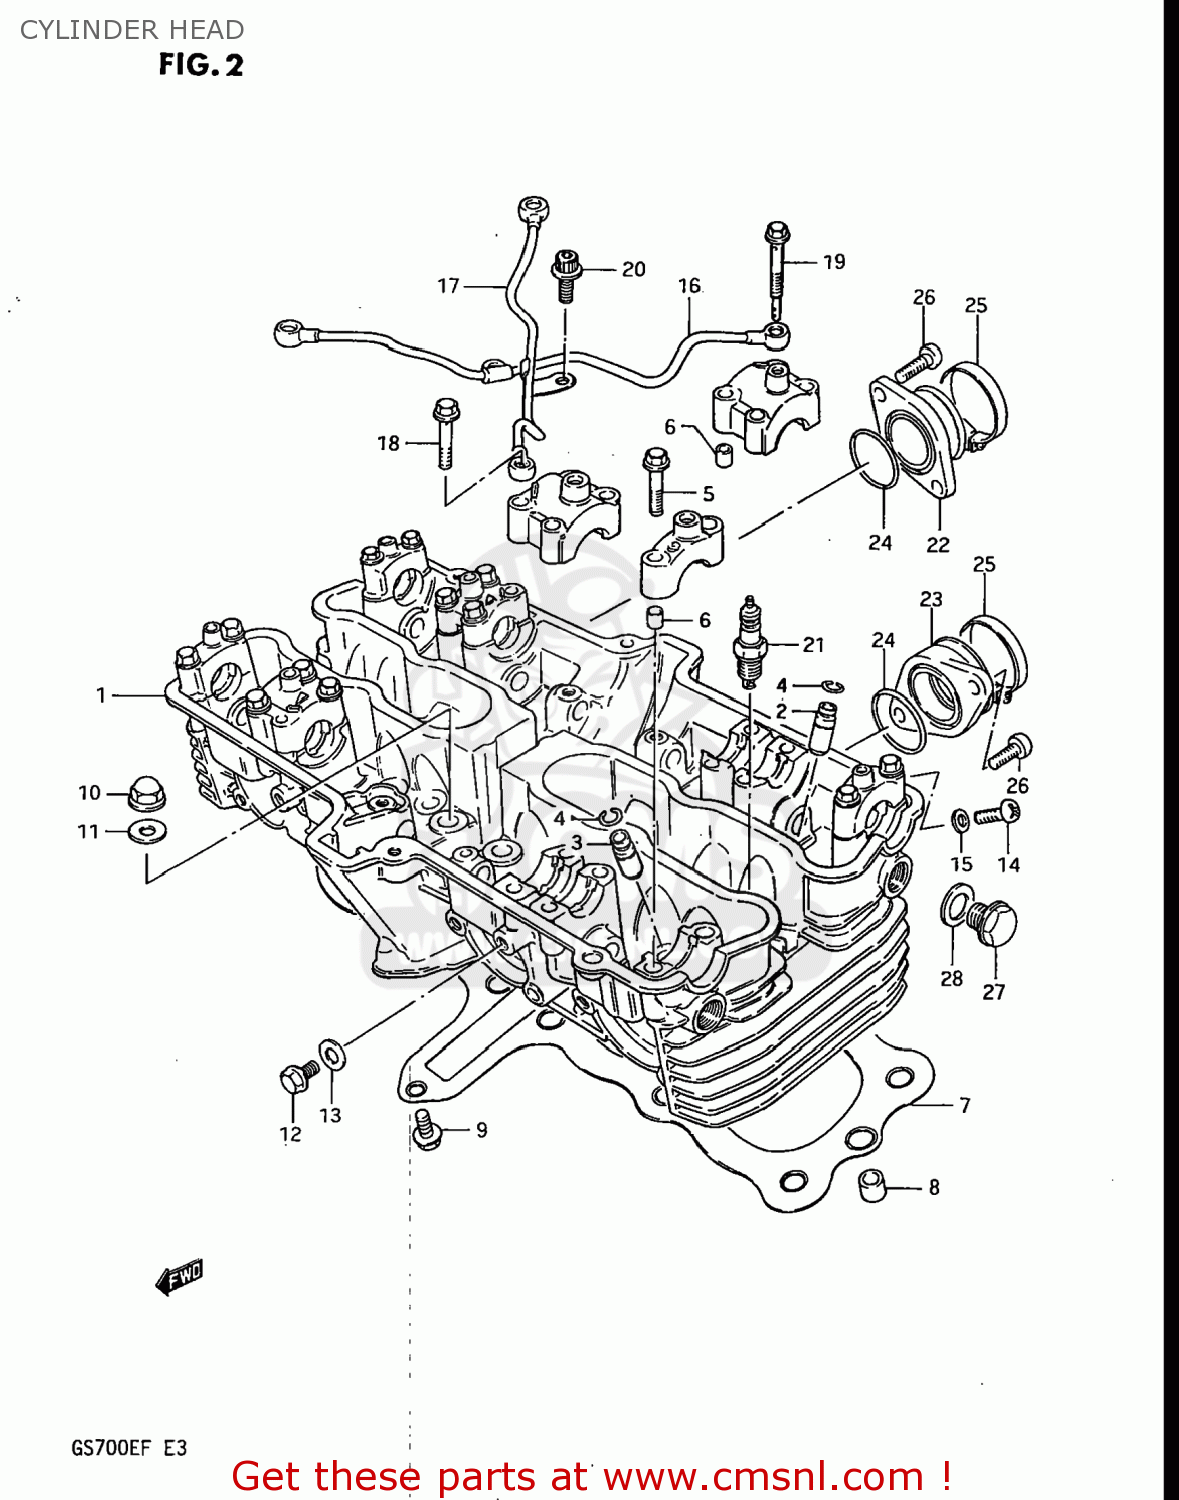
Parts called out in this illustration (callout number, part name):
1	HEAD,CYLINDER
2	GUIDE,INTAKE VALVE
3	GUIDE,INTAKE VALVE
4	RING,SNAP
5	BOLT(6X39)
6	PIN(6.2X8X11)
7	GASKET,CYLINDER HEAD (NAS)
8	PIN
9	BOLT
10	NUT
11	GASKET(10.5X22X2) (NAS)
12	BOLT
13	GASKET(6.2X13X1.2) (NAS)
14	SCREW
15	GASKET(5.3X9.3X1.2) (NAS)
16	PIPE,OIL CYLINDER HEAD NO.1
17	PIPE,OIL CYLINDER HEAD
18	UNION
19	BOLT,UNION
20	BOLT
21	SPARK PLUG D8EA
22	PIPE,INTAKE
23	PIPE,INTAKE
24	O RING(D:2.4,ID:37.7)
25	CLAMP
26	SCREW
27	PLUG
28	GASKET(14X19.2X2) (NAS)
